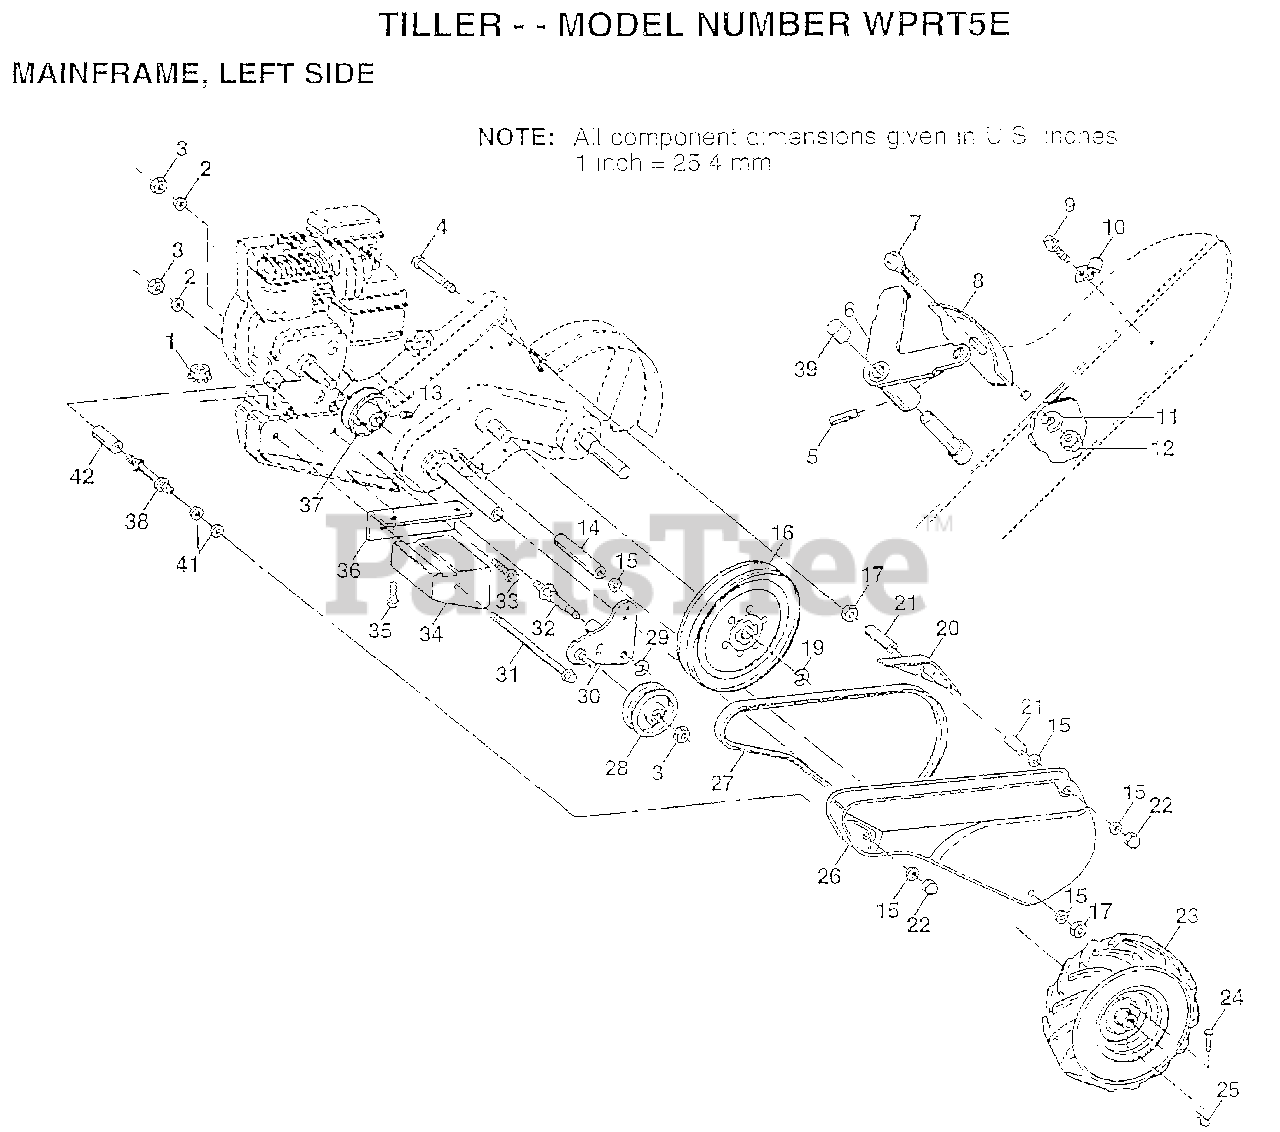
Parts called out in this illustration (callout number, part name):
2	LOCKWASHER
3	NUT.HEX.3/8-16UNC
4	BOLT TI
6	LEVER ASM CRT
7	BOLT
8	PANEL TI
10	CONDIUT CLIP T
11	LOCKWASHER
13	SET SCREW
14	SPACER
15	WASHER
16	SHEAVE.TRANS.
17	NUT.HEX.5/16-18
20	GUARD CRT
21	SPACER.SPLIT
22	NUT TI
23	TIRE TI
24	RIVET.DRILL.1.75
25	RETAINER M
27	BELT-V
28	PULLEY-IDLER TI
29	KLIP RING
31	BOLT CRT
32	SHIFT ARM CRT
33	BOLT
34	COUNTERWEIGHT CRT
35	BOLT
36	BRACKET LH CRT
37	ENGINE PULLEY
38	STUD.GUARD.BELT
39	CAP PLUNGER BLACK
40	NUT
41	WASHER
